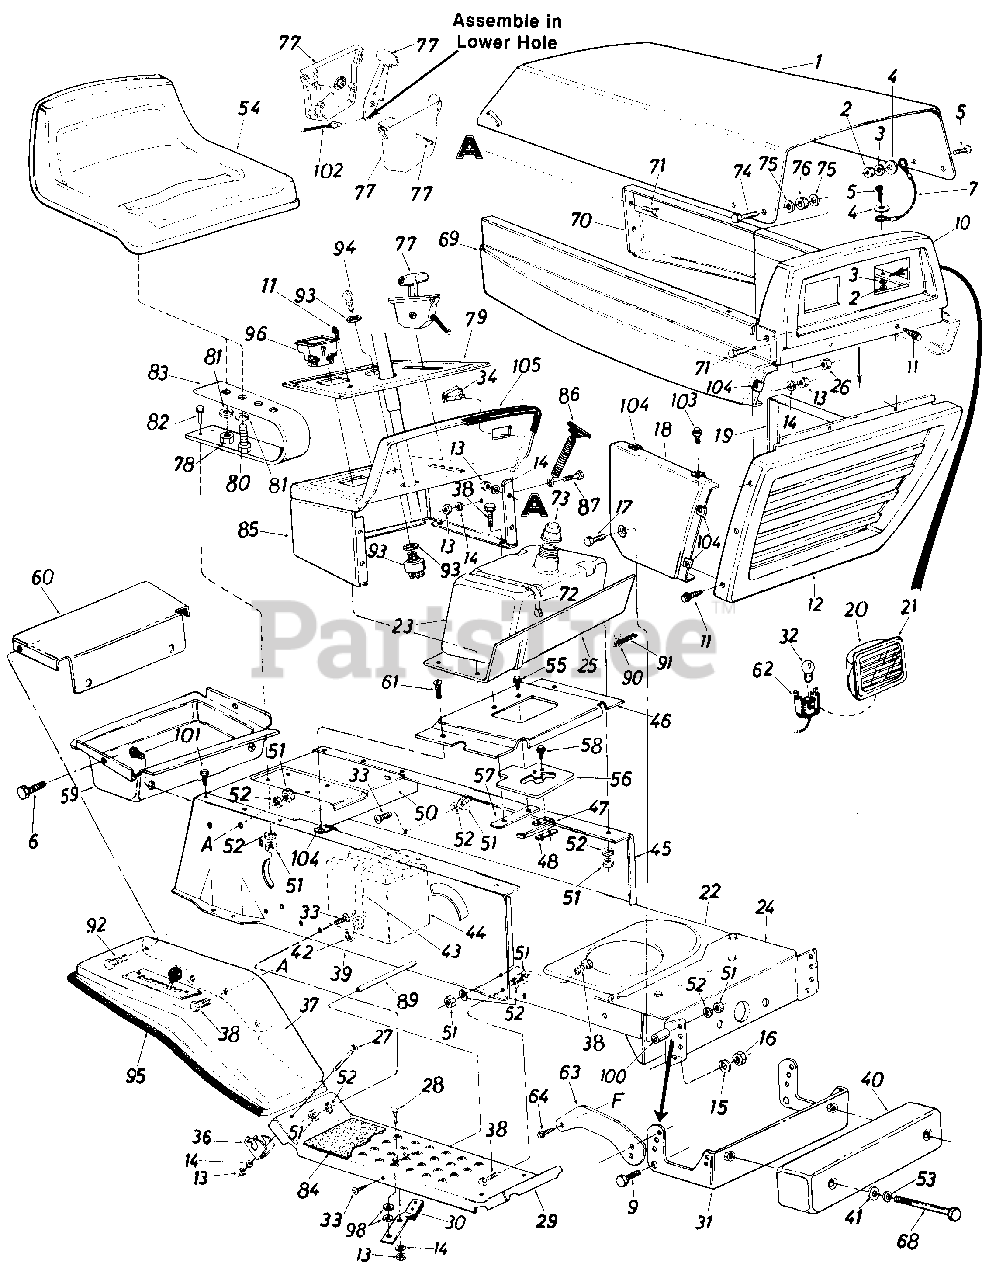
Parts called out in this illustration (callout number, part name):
3	L-Wash. #10 I.D.
4	Fl-Wash. .25" I.D. x .62"
5	Truss Scr. #10-24 x .375"
6	Truss Hd. Scr. #10-24 x .50 "
7	Hood Stop
9	Hex Bolt 7/16-14 x 1.0" Lg.
10	Front Grille Upper Ass'y.
11	Hex AB-Tap Scr. #10 x .50"
14	L-Wash. 1/4" I.D.
15	L-Wash. 7116" I.D.
16	Hex Nut 7/16-14 Thd.
17	Hex Bolt 5/16-18 x 1.50"
18	R.H. Lower Side Panel
19	L.H. Lower Side Panel
20	Headlight Housing
21	Headlight Lens
22	Lower Frame
23	Fuel Tank
24	Front Pivot Brkt.
25	Fuel Tank Support
26	Hex Cent. L-Nut 3/8-16 Thd.
27	Truss Hd. Scr. 1/4-20 x 1 .75 "
28	Carriage Bolt 1/4-20 x .62"
29	Running Board
30	Blade Brake Ass'y.
31	Weight Brkt. Ass'y.
32	Head Lamp
33	Truss Mach. Scr. 5/16-18 x .75" Lg.
34	Light Switch
36	Fender Clamp
37	Fender
39	R.H. Side Frame
40	Counter Weight-38#
41	Fl-Wash .39" I.D.
42	Battery Strap Hook
43	Battery Hold Down Strap
44	12-V Battery
45	L.H. Side Frame
46	Shift Cover
47	Reverse Safety Swith
48	Insulator Nut Plate
50	Hitch Plate
51	Hex Nut 5/16-18 Thd.
52	L-Wash. 5/16" I.D.
53	Bell-Wash. 39" I.D.
54	Seat Ass'y.
55	Truss Mach. Scr. 1/4-20 x .75" Lg.
56	Gear Selection Plate
57	Clamping Plate
58	Hex AB-Tap Scr. #8 x .50"
59	Tool Tray
62	Head Lamp Socket
63	Weight Brkt. Tie Strap
64	Hex Self-Tap Scr. 3/8-16 x .88" Lg.
68	Hex Bolt 3/8-16 x 4.5" Lg.
69	Side Panel-R.H.
70	Side Panel-L.H.
71	Hex Bolt 1/4-20 x .62" Lg.
72	Tie Strap
73	Fuel Cap Gauge
74	Hex Bolt 3/8-16 x 1.00" Lg.
75	Fl-Wash. .380" I.D. x 1.00"
76	Rubber Wash. .33" I.D. x .87" O.D.
77	Throttle Control Box Ass'y.
78	Hex Nut 1/2 -13 Thd .
79	Dash Panel Insert
80	Hex Bolt 1/2-13 x 1.00" Lg.
81	L-Wash. 1/2n I.D.
82	Hex Bolt 5/16-18 x 1.00"
83	Seat Spring
84	Foot Pad
87	Hex Bolt 1/4-20 x .50" Lg.
89	Running Board Rod
90	Hose Clamp
91	Fuel Line
92	Thread Rolling Scr. 1/4-20 x .50" Lg.
93	Ignition Switch
94	Ignition Key
95	Trim Strip
96	Ammeter
98	Fl-Wash. .28" I.D. x .75" O.D. x .06
100	Spacer.379" I.D. x .62" O.D. x .56" Lg.
101	Hex Wash. Hd. AB-Tap Scr. 5/16 x .75" Lg.
102	Throttle Control Wire
103	Hex Wash. Hd. Self-Tap Scr.
104	Speed Nut #10Z
105	Trim Strip-15
